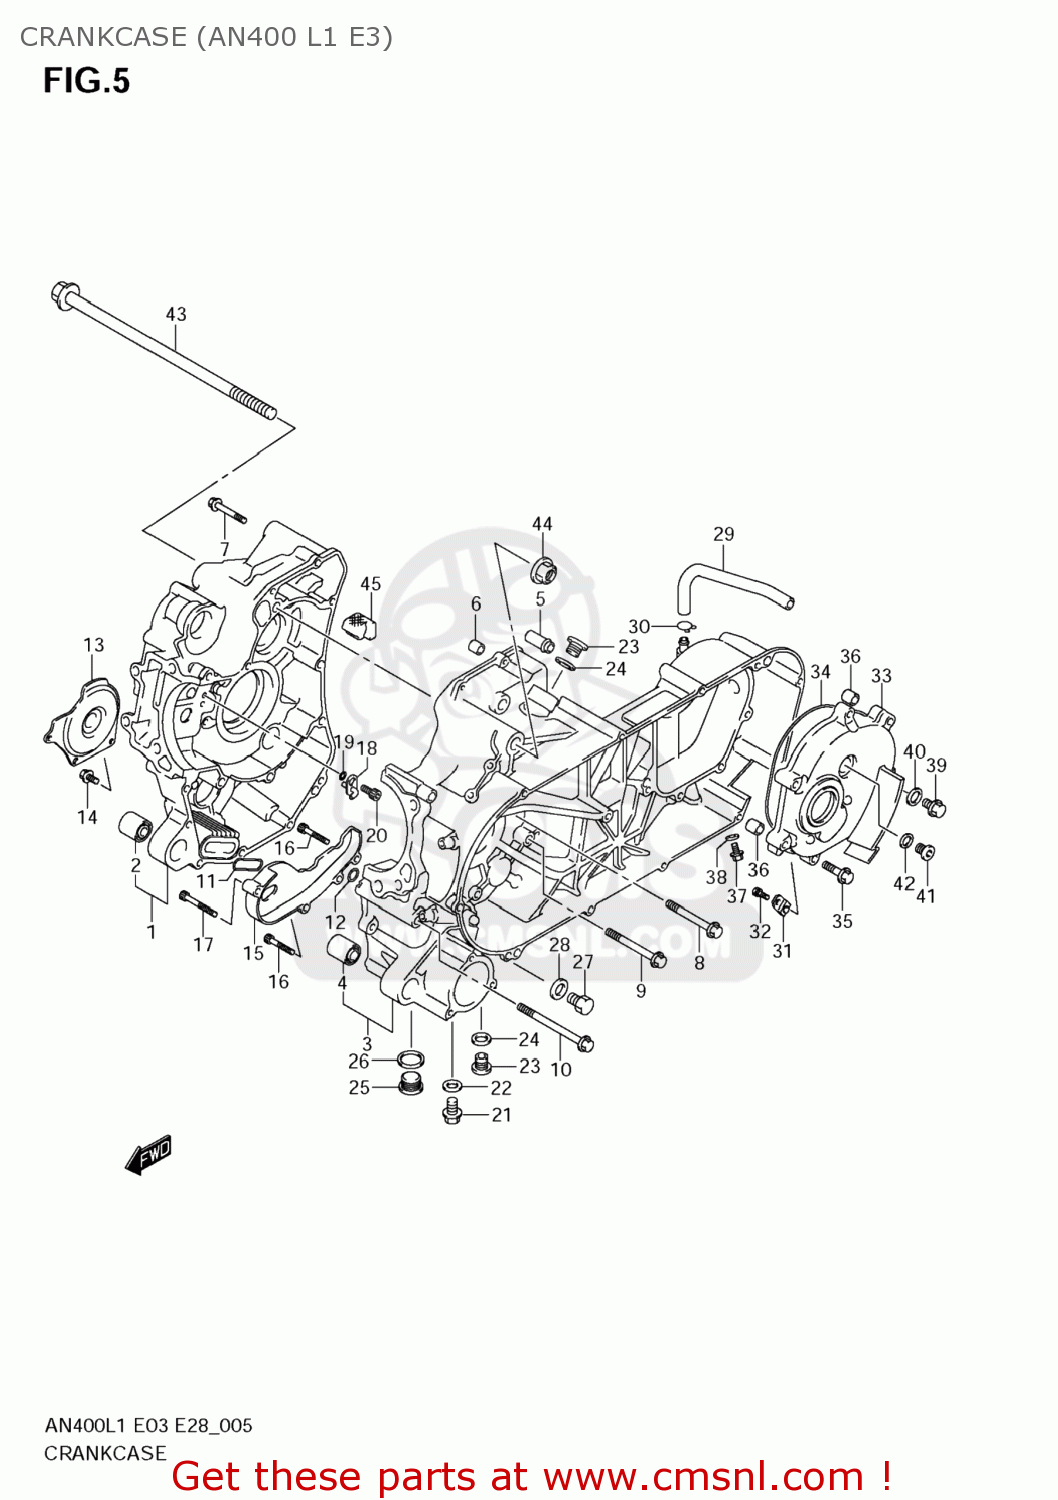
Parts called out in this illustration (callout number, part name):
1	CRANKCASE SET,R
2	BUSH(10X23X30)
3	CRANKCASE SET,
4	BUSH(10X23X30)
5	UNION
6	PIN,CRANKCASE
7	BOLT
8	BOLT
9	BOLT
10	BOLT
11	O RING,CRANKCASE
12	O RING(D:1.9,ID:9.8)
13	SEPARATOR,OIL
14	BOLT
15	SEPARATOR,OIL
16	BOLT
17	BOLT
18	JET,PISTON COOLING
19	O RING(D:1.2,ID:4)
20	BOLT
21	BOLT
22	GASKET(10X14X3.6) (NAS)
23	PLUG,14X12
24	GASKET(13.8X18.8X4.8) (NAS)
25	PLUG,22X11
26	GASKET(22X27X2) (NAS)
27	PLUG(14X20)
28	GASKET(13.8X18.8X4.8) (NAS)
29	HOSE,T/M BREATHER
30	CLIP
31	MAGNETO,GEAR BOX
32	BOLT
33	COVER,GEAR BOX
34	O RING(D:2.4,ID:172)
35	BOLT
36	PIN
37	BOLT
38	GASKET(8.2X14X1) (NAS)
39	BOLT
40	GASKET(10X14X3.6) (NAS)
41	PLUG,16X8
42	GASKET(16X22X2) (NAS)
43	BOLT(12X310)
44	NUT
45	SEPARATOR,OIL BREATHER
